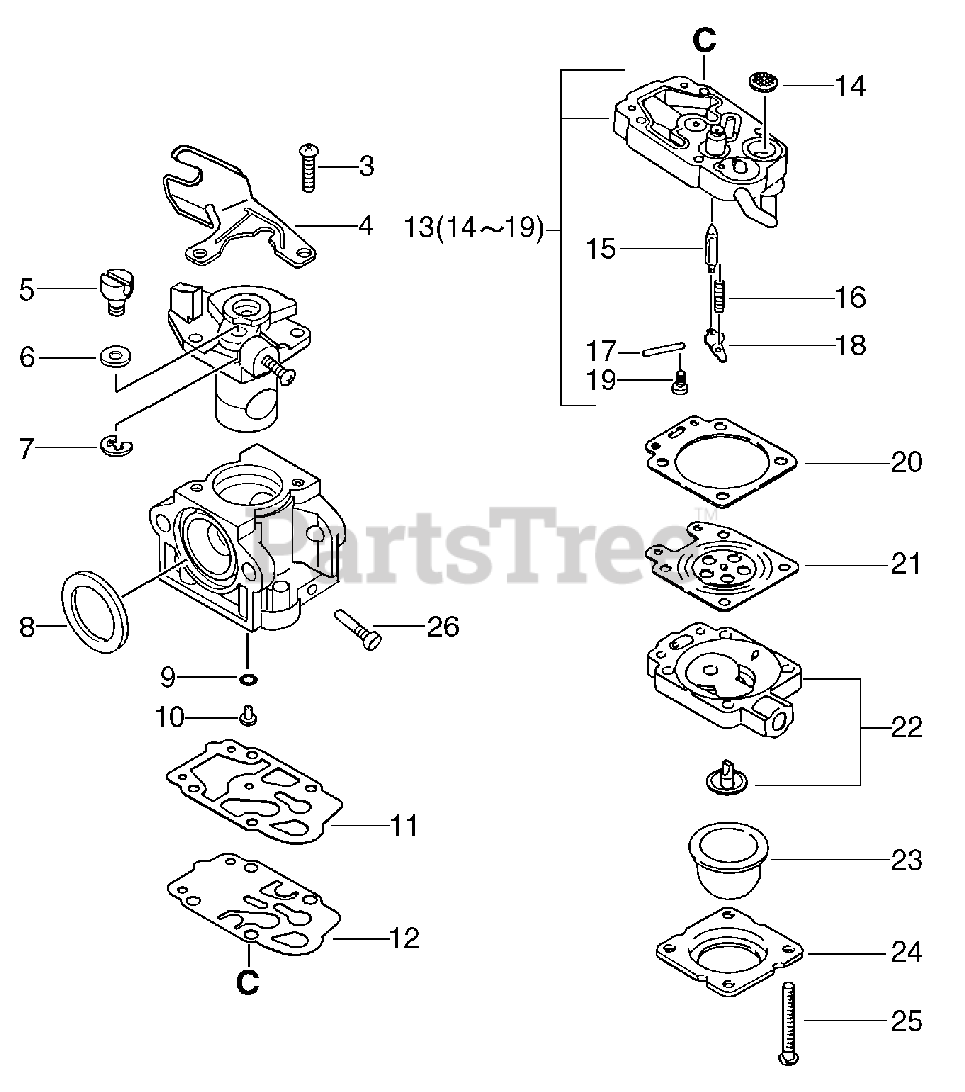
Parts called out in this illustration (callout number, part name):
4	BRACKET, CABLE
7	RING, RETAINING
9	O-RING
11	GASKET, PUMP
12	DIAPHRAGM, PUMP
13	BASE, PURGE
14	STRAINER
15	VALVE, INLET NEEDLE
16	SPRING, METERING LEVER
17	PIN, METERING LEVER
18	LEVER, METERING
19	SCREW, METERING LEVER PIN
20	GASKET, METERING
21	DIAPHRAGM, METERING
22	PURGE BASE ASSY
23	BULB, PURGE
24	RETAINER, PURGE BULB
25	SCREW, PUMP COVER
26	NEEDLE - HIGH SPEED
